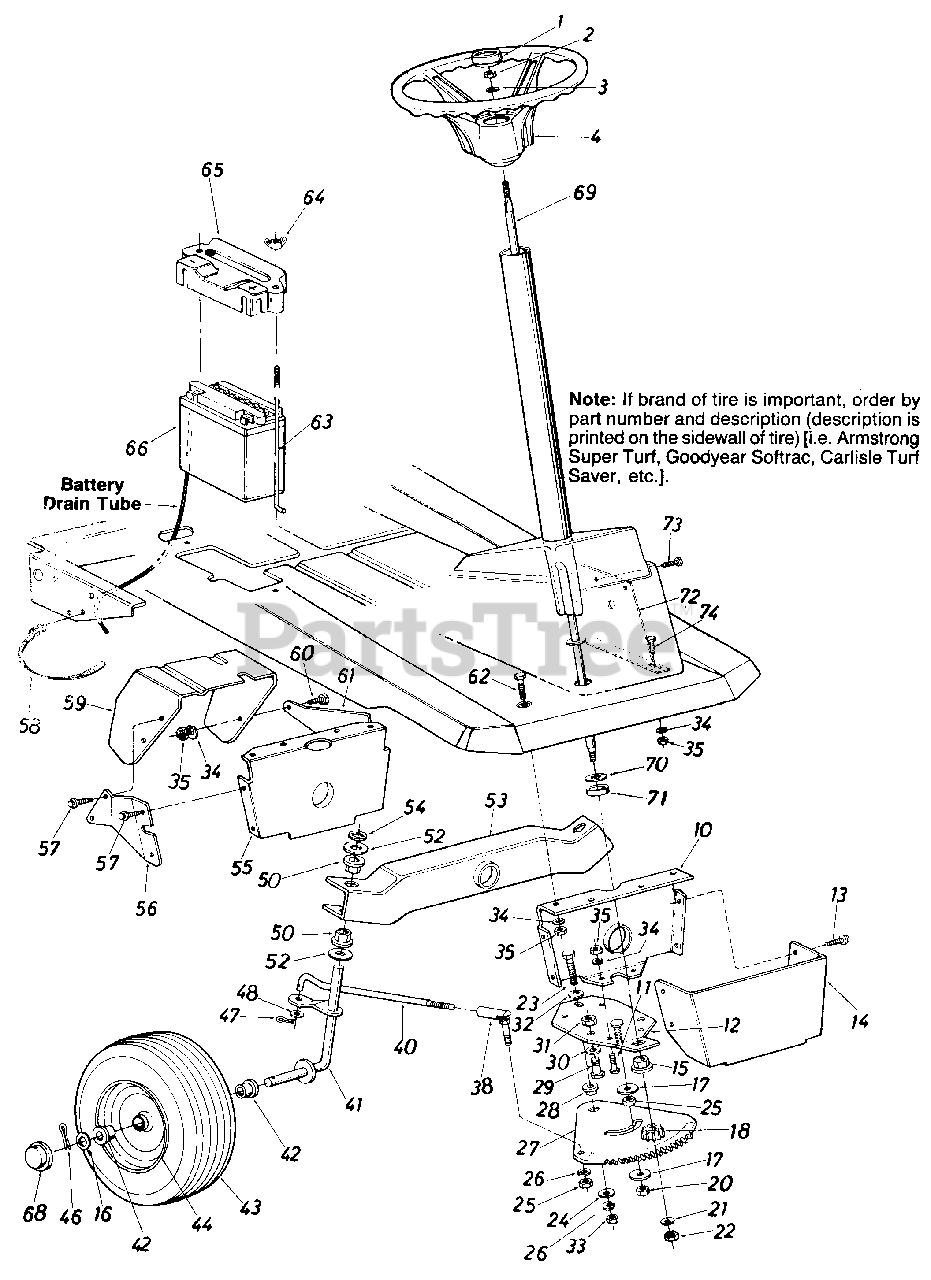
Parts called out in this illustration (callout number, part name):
1	Steering Wheel Cap
2	Hex L-Nut 5/16-24 Thd.
3	Bell-Wash. .345" I.D. x .88" O.D.
4	Steering Wheel Ass'y.
10	Pivot Bar Bracket
11	Hex Bolt 5/16-18 x .75" Lg.
12	Steering Gear Support Brkt.
13	Hex Wash. Hd. AB-Tap Scr. 1/4 x.62" Lg.
16	Fl-Wash. .64" I.D. x 1.5" O.D.
17	Fl-Washer 3/8" I.D. x 1.37" O.D.
18	Steering Pinion Gear
20	Hex L-Nut 3/8-24
21	Fl-Wash. .34" I.D. x .68" O.D.
22	Hex L-Nut 5/16-24 Thd.
23	Hex Bolt 3/8-24 x 1.5" Lg. (Grade 5)
24	Fl-Wash. .385" I.D. x 1.38"
25	Hex Nut 3/8-24 Thd.
26	L-Wash. 3/8" I.D.
27	Steering Gear Segment
28	Shoulder Spacer .622" Dia. x .218
29	Hex Bolt
30	Fl-Wash. .530" I.D. x .930
31	Hex Nut 1/2-13 Thd.
32	Bell-Wash. .385" I.D. x .88"
33	Hex Nut 3/8-24 Thd.
34	L-Wash. 5/16" I.D.
35	Hex Nut 5/16-18 Thd.
38	Ball Joint Ass'y. 3/8-24 Thd.
40	Steering Tie Rod
41	Front Axle Ass'y. R.H.
42	Flange Bearing .632" I.D.
43	Front Wheel Ass'y. Comp.
44	Front Wheel Rim Only
46	Cotter Pin 118" Dia. x 1.25"
47	Cotter Pin 1/8" Dia. x 1.00"
48	Fl-Wash. .385" I.D. x .87"
50	Hex Flange Bearing
52	Fl-Wash. .635" I.D. x 1.12"
53	Pivot Bar Ass'y.
54	Speed Nut 5/8" I.D.
55	Pivot Bar Bracket
56	Bracket Reinforcement R.H.
57	Hex Wash. Hd. AB-Tap Scr. 1/4 x .62" Lg.
58	Cable Tie
59	Clutch-Brake Pedal Ass'y.
60	Hex Bolt 5/16-18 x .75" Lg.
63	Battery Hold Down Rod
64	Wing Nut Solid 1/4-20 Thd.
65	Battery Hold Down Cover
66	12V Battery
68	Hub Cap
69	Steering Shaft Ass'y.
70	Fl-Wash. .62" I.D. x 1.25" O.D.
71	Spacer (Plastic)
74	Hex Bolt 5/16-18 x 2.00" Lg.
